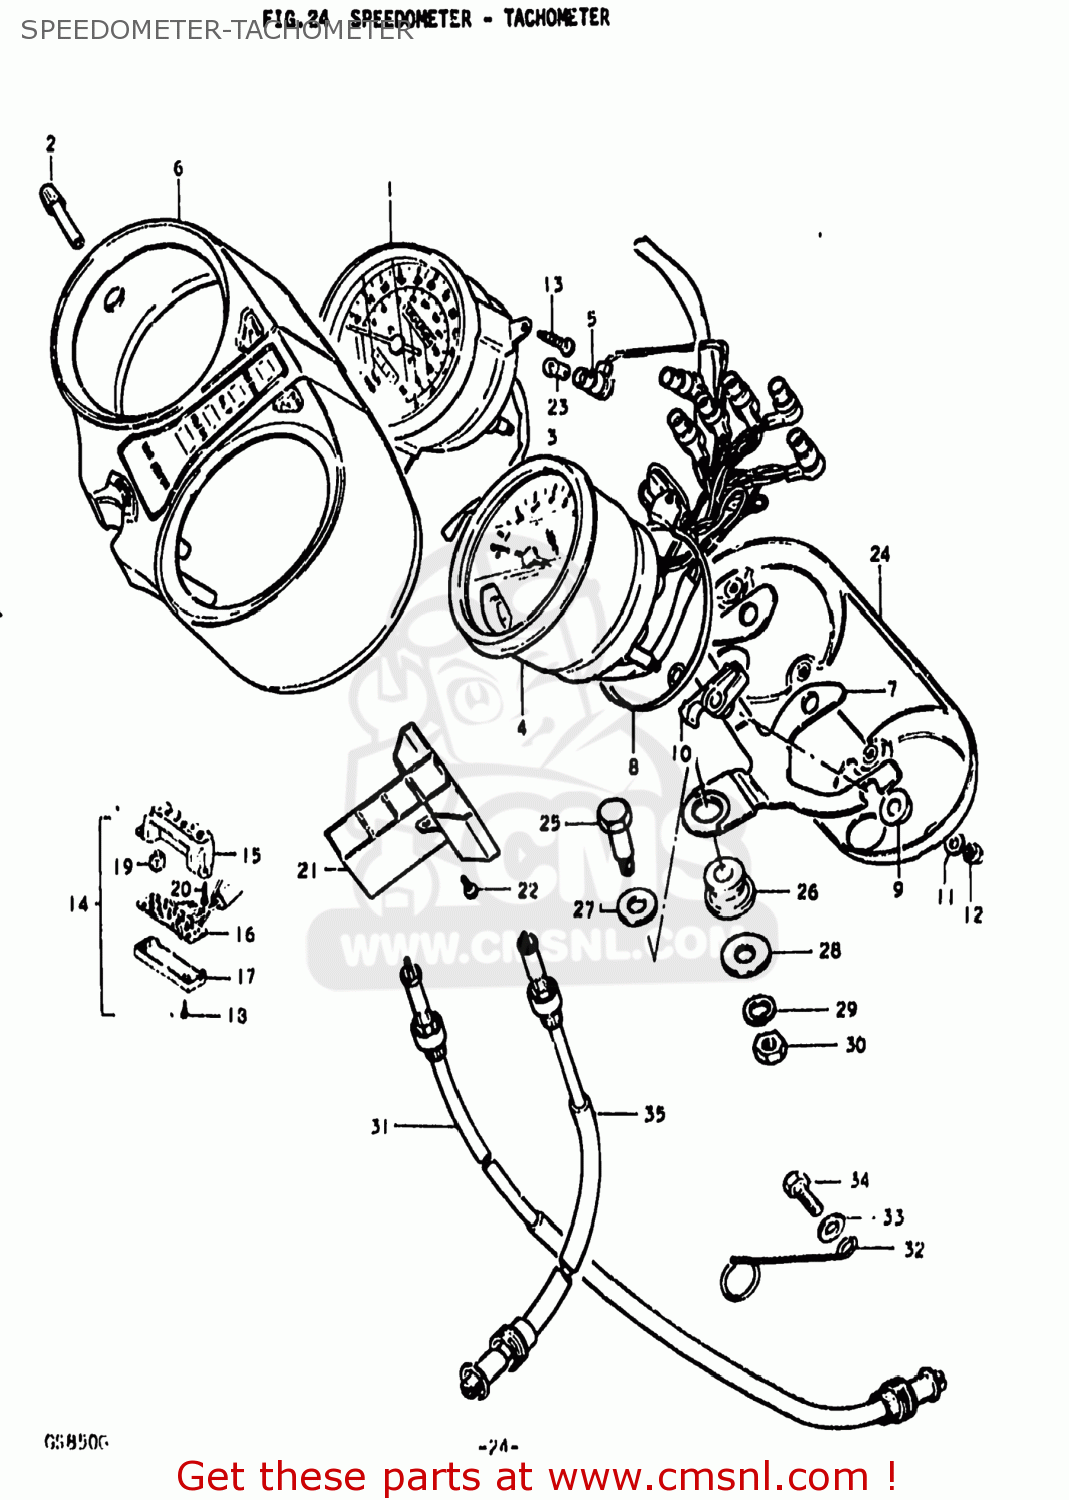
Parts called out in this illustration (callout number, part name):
1	SPEEDOMETER ASSEMBLY
2	KNOB
3	WIRE,LEAD
4	TACHOMETER
5	SOCKET,METER
6	CASE
7	BRACKET,COMBINATION METER
8	PLATE,METER,UNDER
9	CUSHION,METER (A)
10	CUSHION,METER (B)
11	WASHER,METER
12	NUT
13	SCREW
14	INDICATOR ASSEMBLY,GEAR POSITION
15	CASE,GEAR INDICATOR
16	SOCKET,GEAR INDICATOR
17	COVER,LWR
18	SCREW,GEAR INDICATOR
19	BULB(14V1.12W)
20	SCREW
21	CASE,PILOT BULB
22	SCREW
23	BULB(12V3.4W,STANLEY,A72A)
24	COVER,UNDER
25	BOLT(8X31)
26	CUSHION,METER
27	WASHER
28	WASHER (8.5X29X1.6)
29	LOCK WASHER
30	NUT
31	CABLE ASSEMBLY,SPEEDOMETER
32	GUIDE,SPEEDOMETER CABLE
33	WASHER 6MM
34	BOLT, UPPER
35	CABLE ASSEMBLY,TACHOMETER
